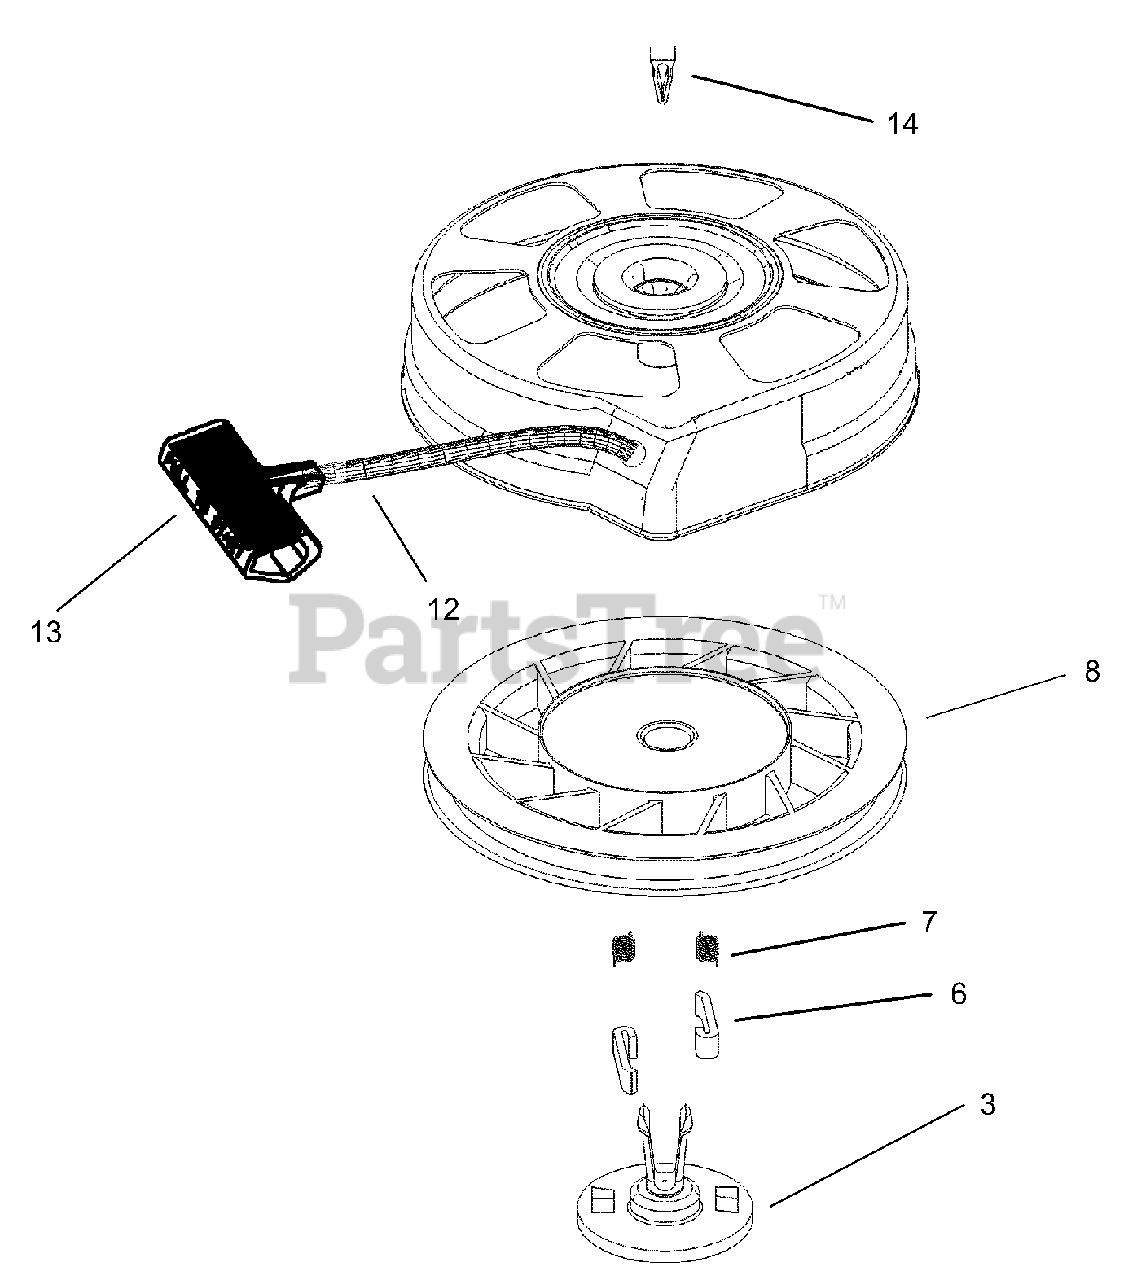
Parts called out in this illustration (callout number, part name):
3	Retainer
6	Starter Dog
7	Dog Spring
8	Pulley & Rewind Spring Ass'y
11	Starter Housing Ass'y (40 degree grommet)
12	Starter Rope (Length 98" x 9/64" dia.)
13	Starter Handle
14	Spring Clip
